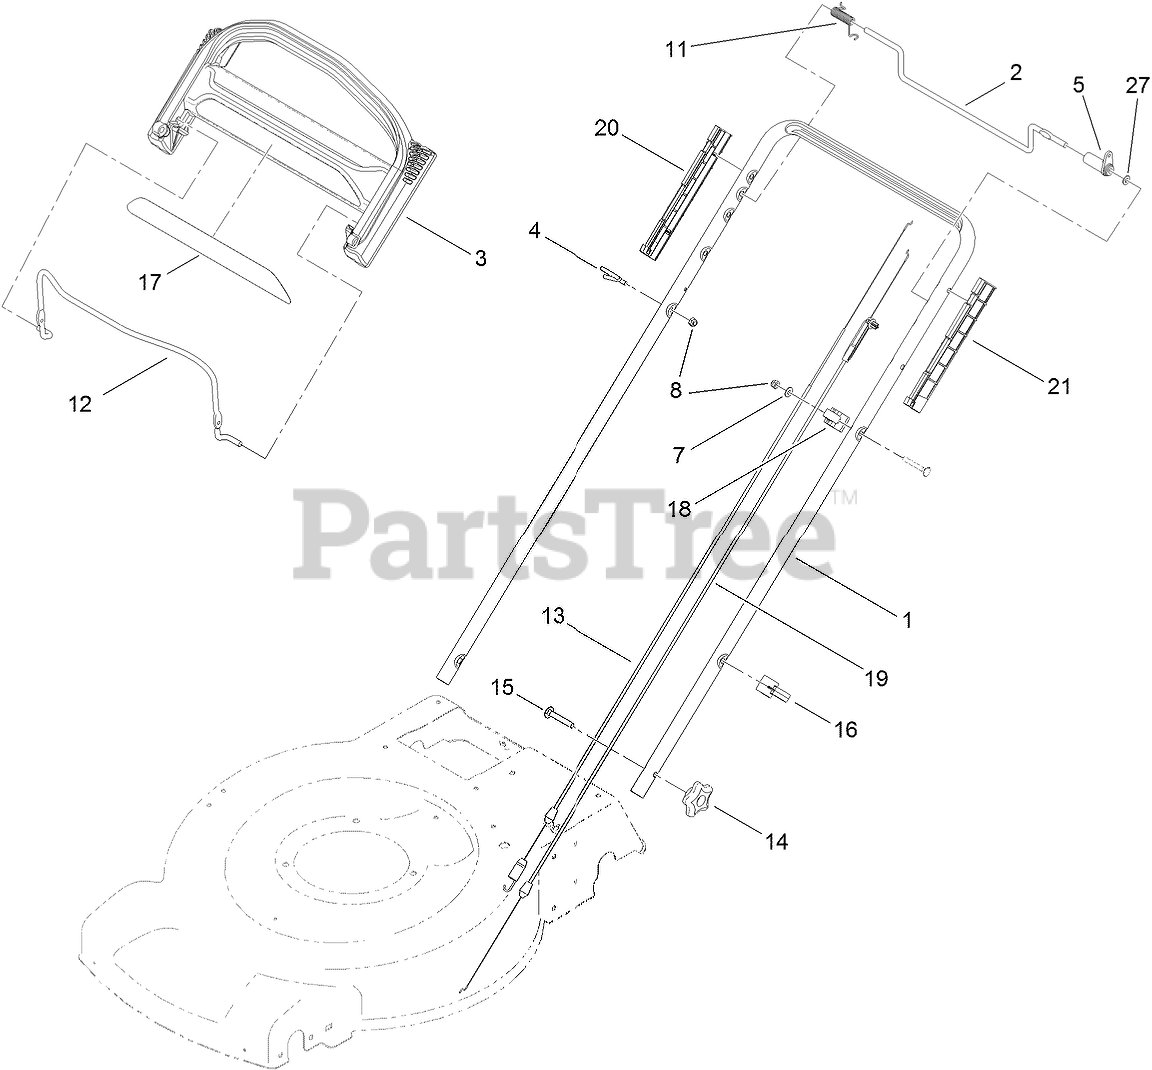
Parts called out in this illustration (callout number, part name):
2	BAR-CONTROL, TRACTION
3	HANDLE-CONTROL
4	GUIDE-ROPE
5	LEVER-TRACTION
7	WASHER-FLAT
8	NUT-LOCK, NI
11	Spring-Torsion
12	Bail-Brake
13	CABLE-TRACTION
14	KNOB-HANDLE
15	Screw-CARR
16	GUIDE-CABLE
17	DECAL-HANDLE
18	ANCHOR-CABLE
19	CABLE-BRAKE
20	GUIDE-RH
21	GUIDE-LH
27	WASHER-PLAIN
